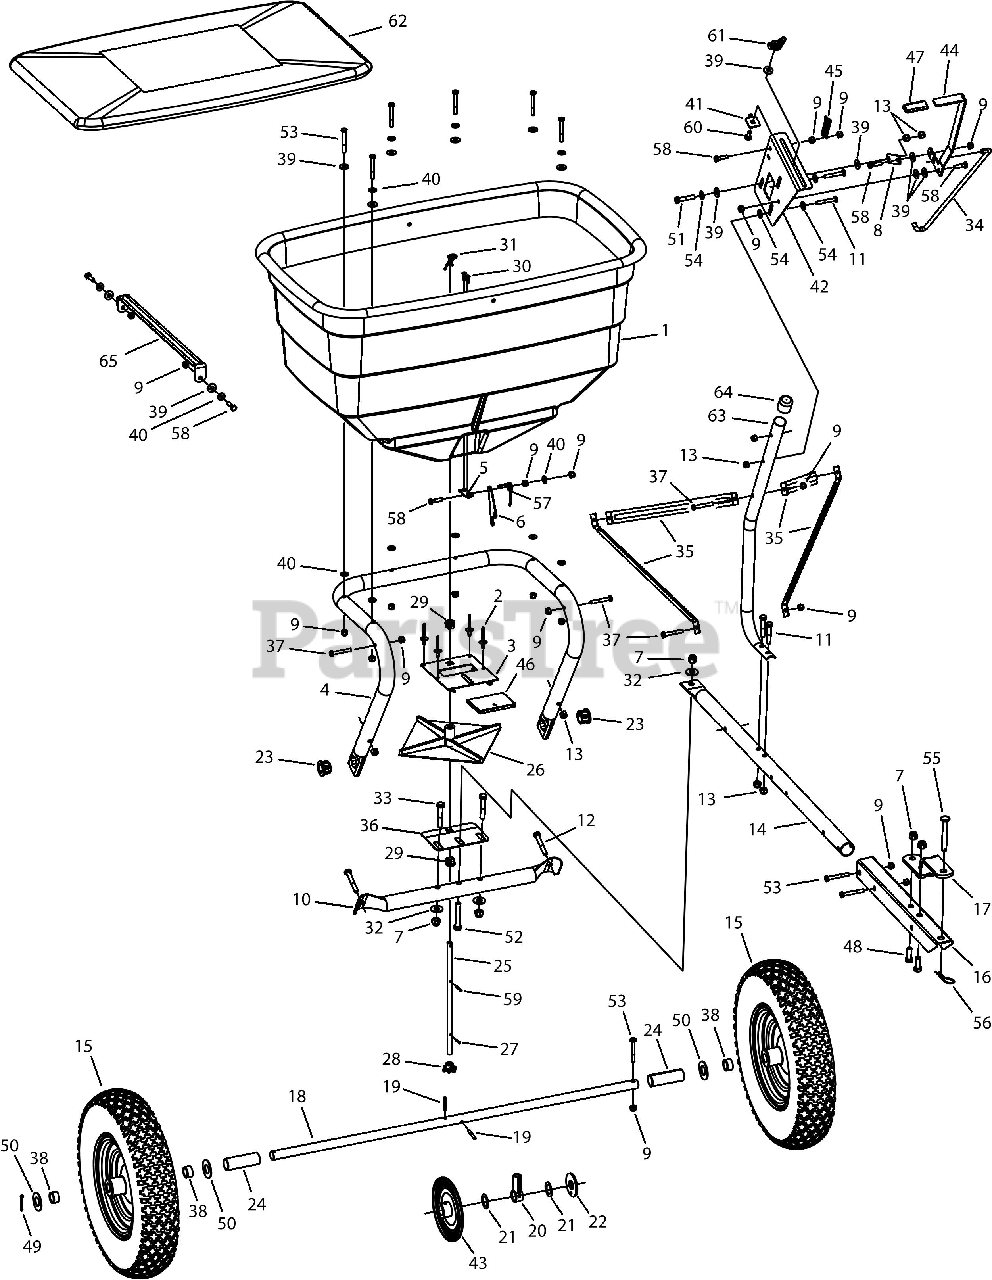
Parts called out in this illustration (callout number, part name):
2	Rivet, Stainless
3	Guide Closure Assembly
4	Frame Tube
5	Slide Gate Angle Bracket
6	Slide Gate Bracket
7	Nylock Hex Nut, 3/8-16
8	Flow Control Link
9	Nylock Hex Nut, 1/4-20
10	Crossover Tube
11	Hex Bolt, 5/16-18 x 1-3/4"
12	Hex Bolt, 5/16-18 x 2"
13	Nylock Hex Nut, 5/16-18
14	Hitch Tube
16	Hitch Extension Bracket
17	Hitch Bracket
18	Axle Shaft
19	Spring Pin, 3/16 x 3-1/4"
20	Axle Shaft Bushing
21	Flat Washer, .78"
22	Flat Washer, 1/2"
23	Flange Bearing
24	Spacer Tube
25	Sprocket Shaft
26	Spreader Plate
27	Spring Pin, 1/8 x 5/8"
28	6 Tooth Sprocket
29	Delrin Bushing
30	Rivet
31	Hairpin Agitator
32	Flat Washer, 3/8"
33	Hex Bolt, 3/8-16 x 2"
34	Flow Control Rod
35	Hitch Brace
36	Shaft Support Plate
37	Hex Bolt, 1/4-20 x 1-3/4"
38	Ball Bearing
39	Nylon Washer
40	Flat Washer, 1/4"
41	Adjustable Stop
42	Flow Control Mount Bracket
43	Gear Assembly
44	Flow Control Arm
46	Closure Plate
47	Flow Control Arm Grip
48	Hex Bolt, 3/8-16 x 1"
49	Cotter Pin, 1/8" x 1-1/2"
50	Flat Washer, 3/4"
51	Hex Bolt, 5/16-18 x 1-1/2"
52	Hex Bolt, 3/8-16 x 2-1/4"
53	Hex Bolt, 1/4-20 x 2"
54	Washer, 5/16"
55	Hitch Pin
56	Hair Cotter Pin, 1/8"
57	Torsion Spring
58	Hex Bolt, 1/4-20 x 1"
59	Spring Pin, 1/8 x 1"
60	Carriage Bolt, 1/4-20 x 3/4"
61	Nylon Wing Nut
62	Vinyl Cover
63	Flow Control Mounting Tube
64	Vinyl Cap
65	Hopper Strap
769-11328	Owners Manual
